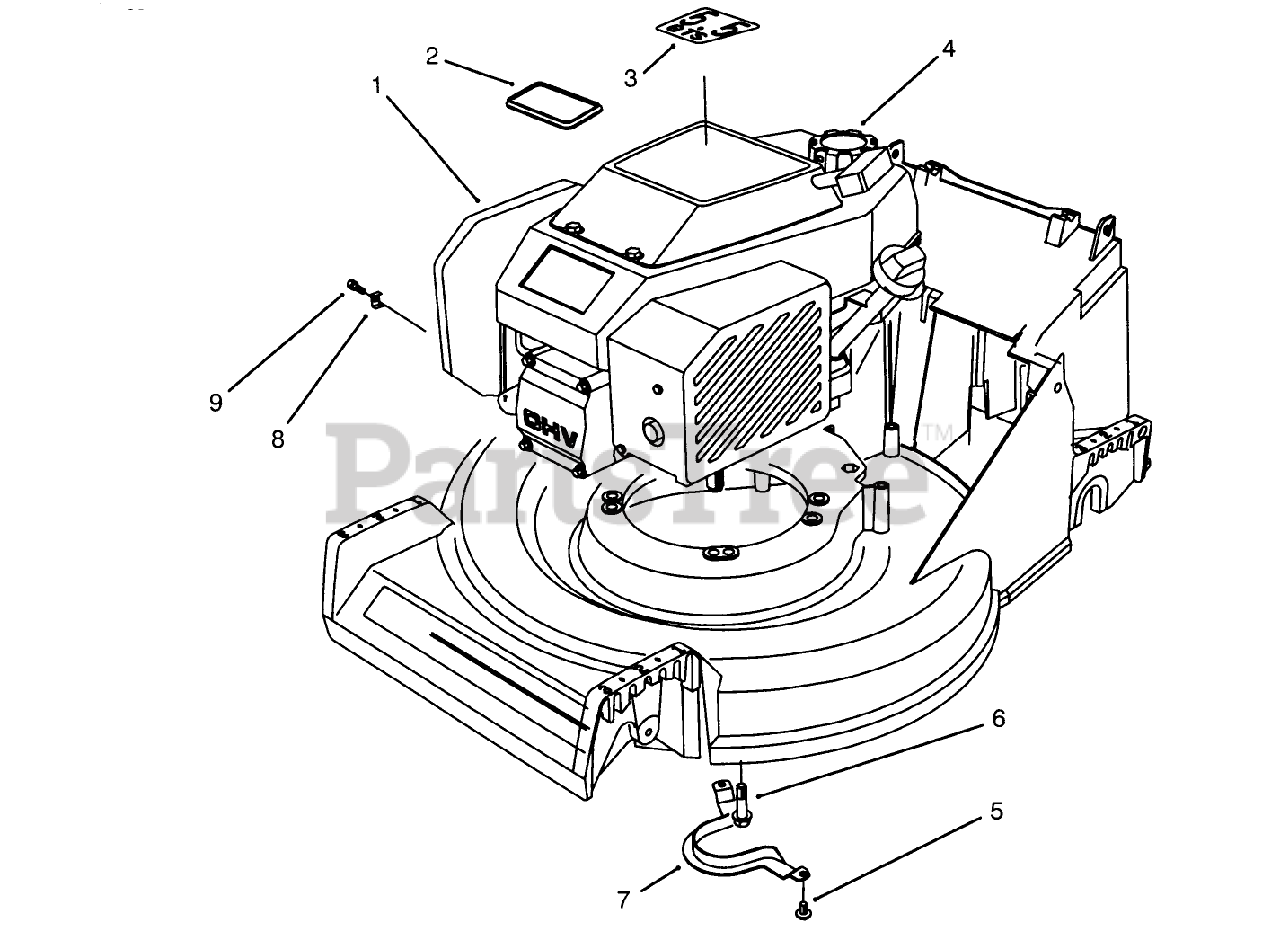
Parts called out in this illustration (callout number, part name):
1	Engine-OHV (Incl. Ref. #2 & 4)
2	PLATE-LOGO
3	DECAL - ENGINE
4	CAP-GAS
5	SCREW-HWHTF
6	SCREW-HWH
7	Guide-Belt
8	CLAMP-CASING
9	CLAMP SCREW F/W ENGINE
